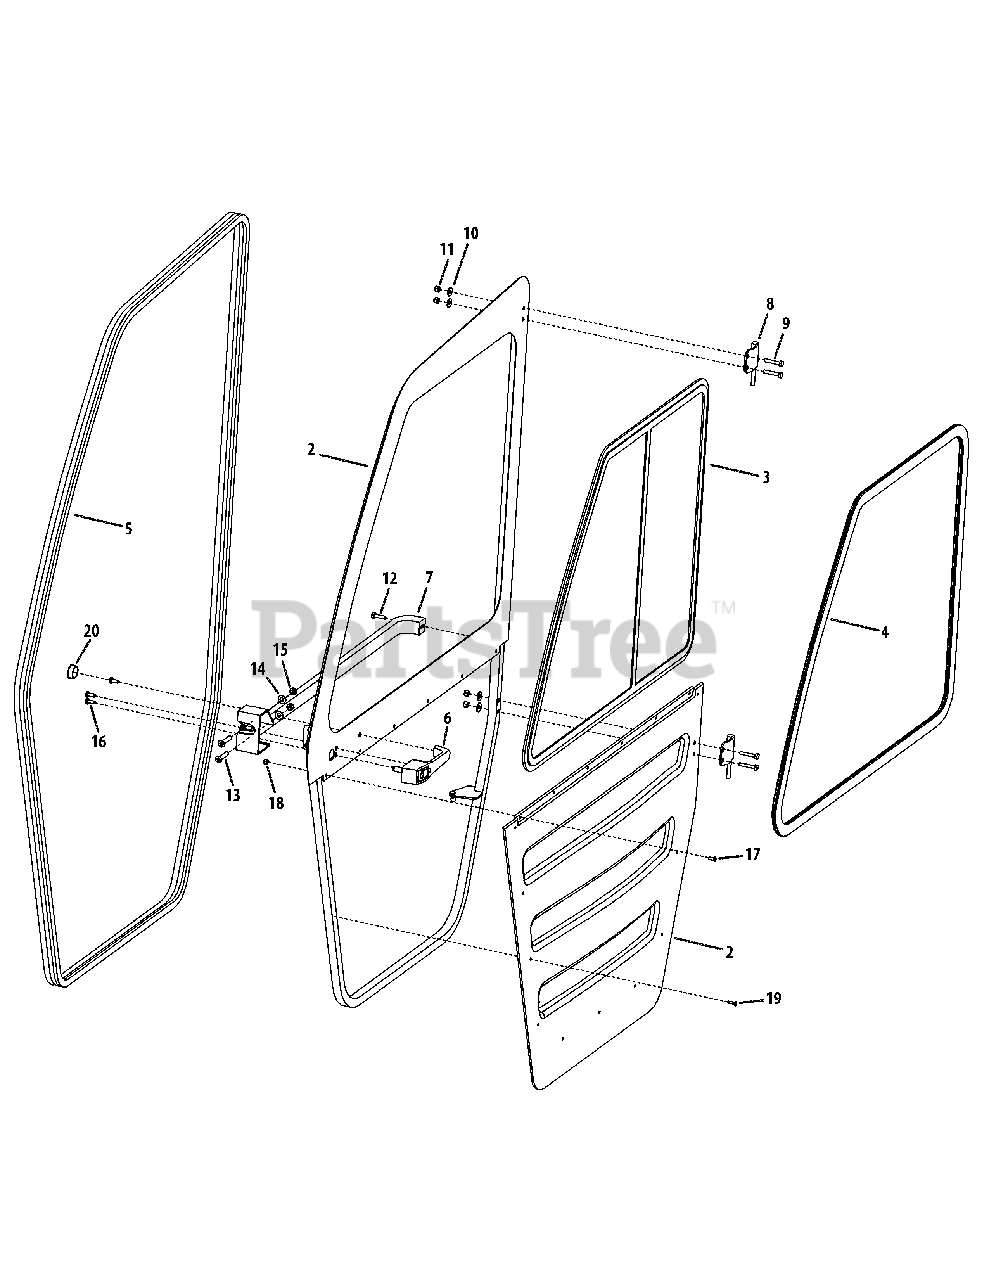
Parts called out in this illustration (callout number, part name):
2	Door Frame with lower Panel, LH
3	Sliding Window, Temp. Glass
4	Window Mounting Rubber - 10’
5	1-1/2" Side Bulb & 2 Wipers - 15’
6	Outside Handle (Set Of 2)
7	Door Latch LH - Non Locking
8	Tube Frame Hinge, LH
9	Hex Bolt, 1/4-20 x 1 1/2"
10	Washer, 1/4"
11	Locknut, 1/4-20
12	Hex Bolt, 1/4-20 x 3/4"
13	Hex Bolt, 5/16-18 x 1 1/2"
14	Washer, 5/16
15	Locknut, 5/16-18
16	Hex Bolt, M6 x 12mm
17	Hex Bolt, 10-32 x 1/2"
18	Locknut, 10-32
19	Screw, #10 x 3/4"
20	Hole Plug, 1"
